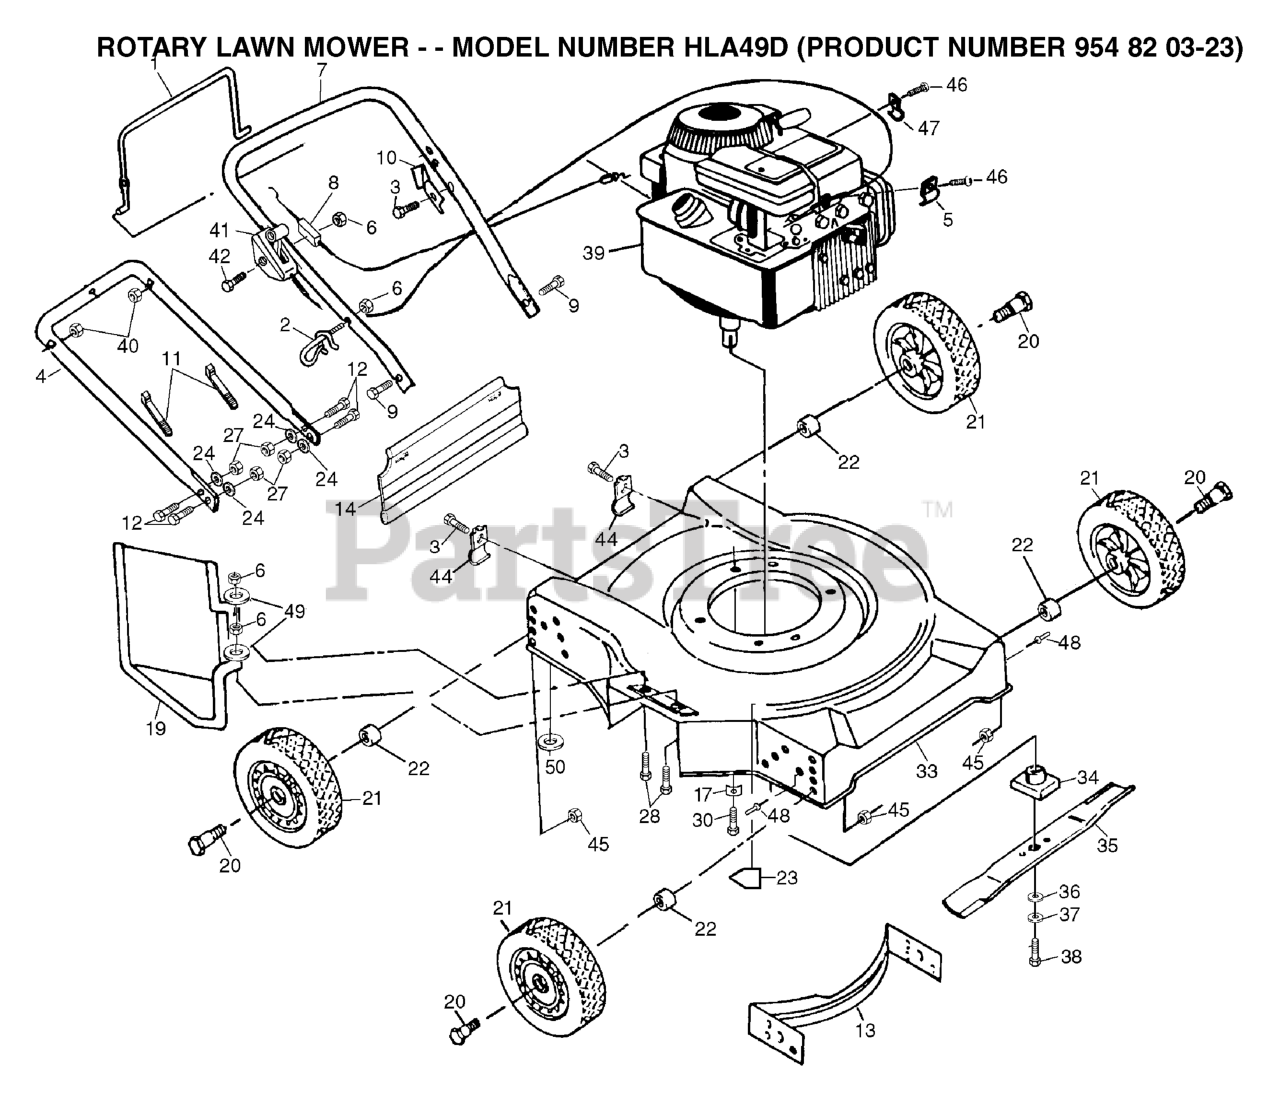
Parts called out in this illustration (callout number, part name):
1	CONTROL BAR
2	ROPE, GUIDE
3	TAPPING SCREW
5	WASHER
6	NUT
8	CABLE.CONTROL.MZR.RH.SP/PUSH
9	BOLT
10	BRACKET UPSTOP
11	TIE GUIDE
13	BAFFLE
14	REAR SKIRT
17	WASHER.ENGINE.BZP
21	WHEEL
22	SPACER.WHEEL.390.X1.0X.380.RTA
23	DANGER DECAL
27	FLANGED LOCKNUT 3/8-16 ZINC
28	BOLT.HEX.1/4.X.3/4.DICHROMATE
30	BOLT 3/8-16X1-1/8
34	BLADE ADAPTOR
35	BLADE.20.MULCH.(50DK,6020MD)
36	WASHER,HARDEN
37	LOCKWASHER
38	SCREW, HEX HD 3/8-24 X 1-3/8
40	NUT
41	THROTTLE CONTROL
42	SCREW.PAN.HEAD
44	BRACKET DEFL PM
45	LOCKNUT PM
46	SCREW.HEX.HEAD.WASHER.10-16
47	GUIDE CLIP PM
48	RIVET BLIND
49	WASHER
50	WASHER
